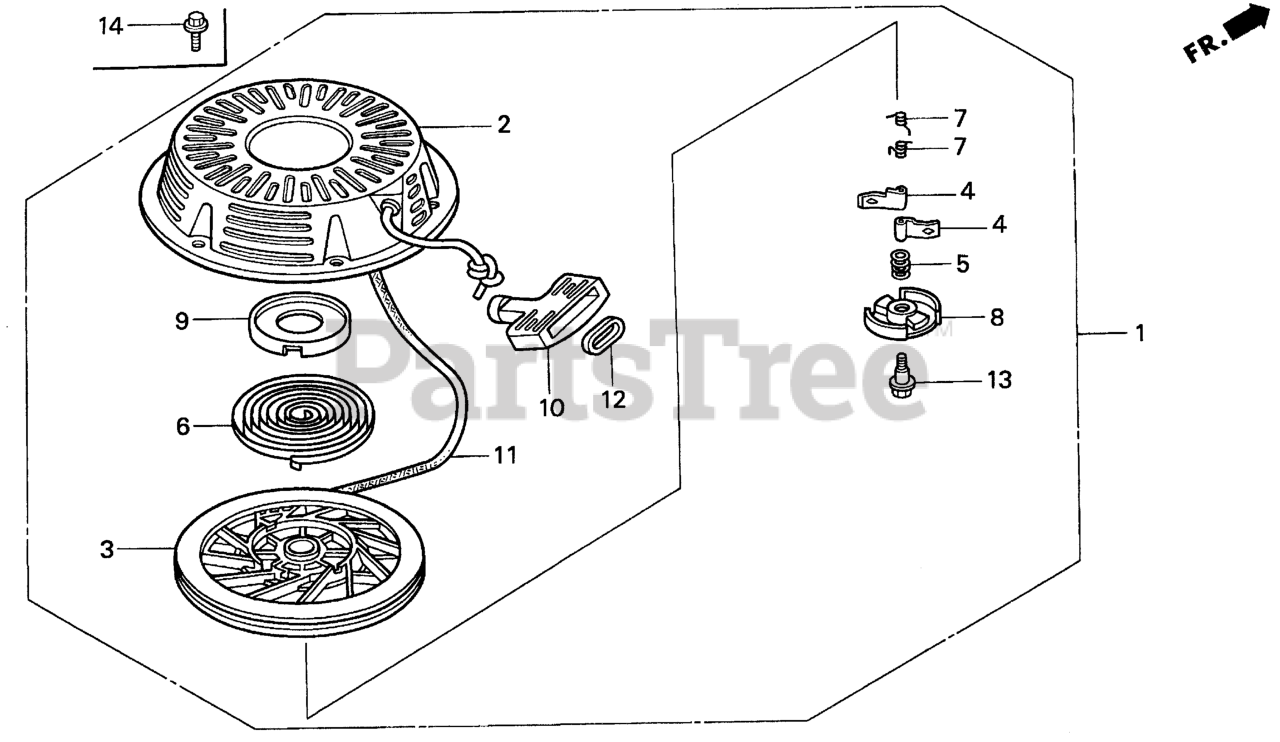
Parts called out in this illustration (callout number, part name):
1	STARTER ASSY., RECOIL *R280* (POWER RED)
2	CASE, RECOIL STARTER *R280* (POWER RED)
3	PULLEY, RECOIL STARTER
4	RATCHET, STARTER
5	SPRING, FRICTION
6	SPRING, STARTER RETURN
7	SPRING, RATCHET
8	RETAINER, SPRING
9	HOLDER, SPRING
10	GRIP, STARTER
11	ROPE, RECOIL STARTER (#6X64") (N/A: USE P/N 08560-ZG921-11)
12	GRIP, REINFORCEMENT
13	SCREW, CENTER
14	BOLT, FLANGE (6X10)
